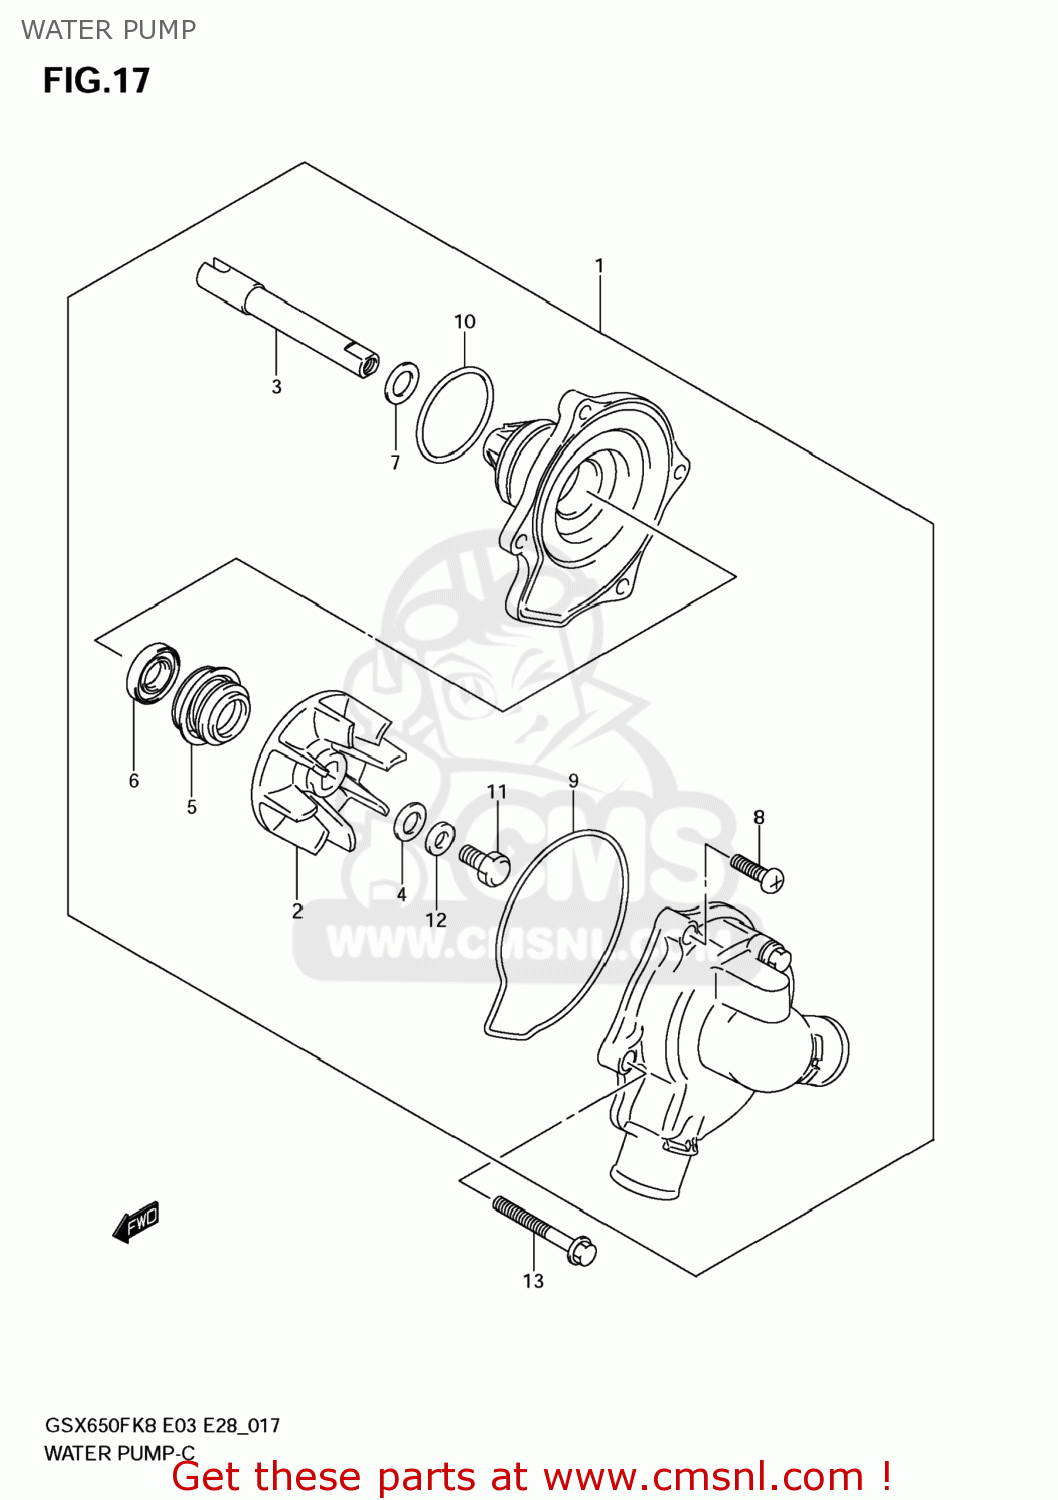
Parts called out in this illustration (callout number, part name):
1	PUMP ASSY,WATER
2	IMPELLER
3	SHAFT
4	GASKET(6X15X2.2) (NAS)
5	SEAL,MECHANICAL
6	SEAL,OIL
7	WASHER
8	SCREW
9	O RING
10	O RING,WATER PUMP HOLDER
11	BOLT(6X13)
12	WASHER
13	BOLT
